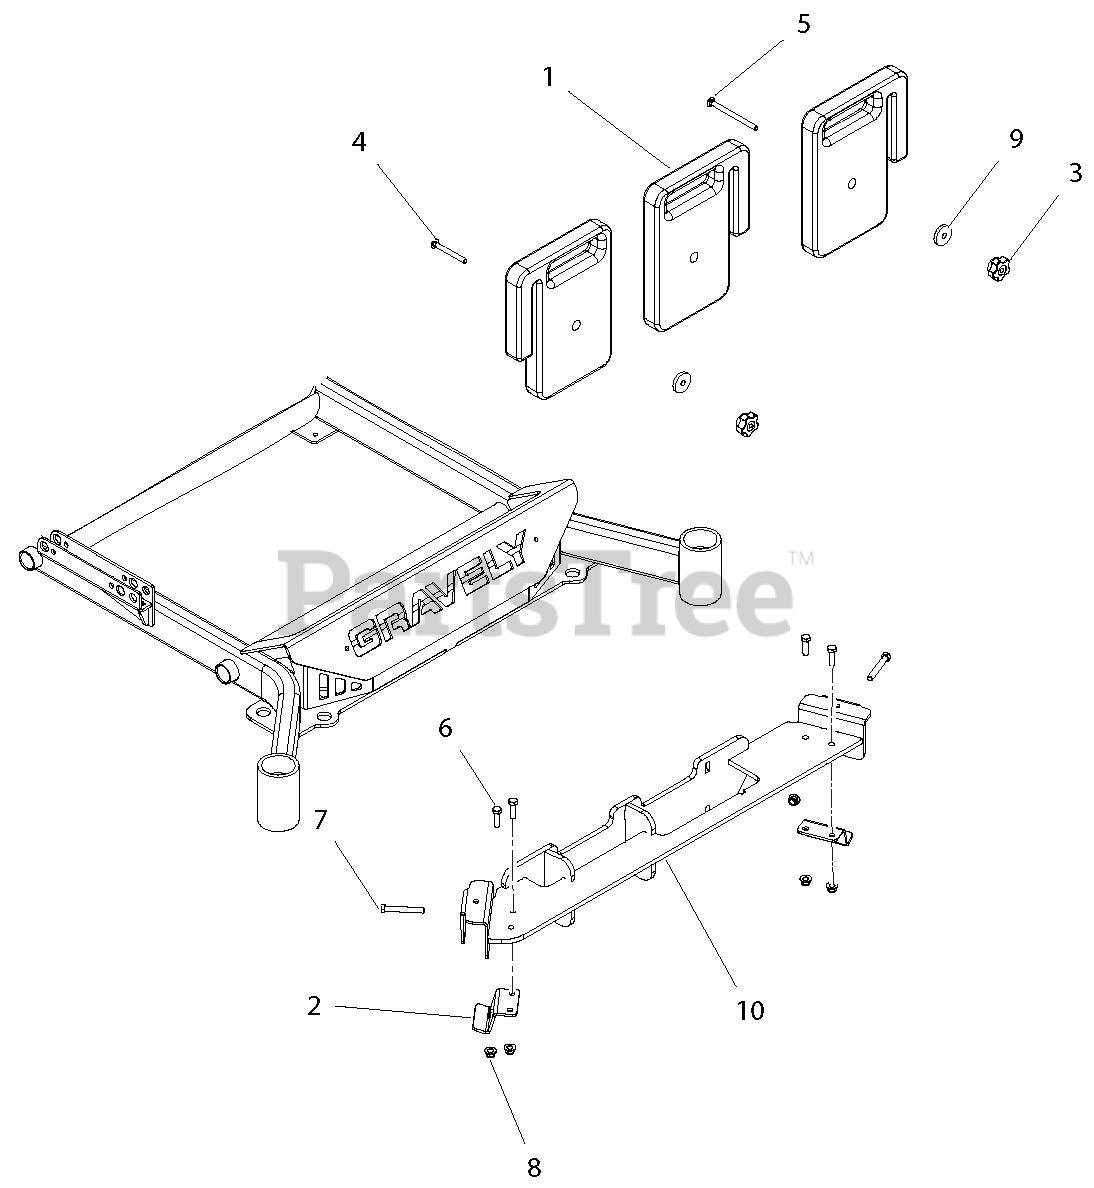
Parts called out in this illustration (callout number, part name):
1	WEIGHT, REAR
2	CLAMP, WEIGHT PLATE
3	KNOB, CLAMPING
4	@BLT-RDHDSQNK .31-18X3.00 G5YZ
5	BLT-RDHDSQNKFTH .31-18X4.50 G5
6	@BLT-HEX .38-16X1.25 GR5 YWZC
7	@BLT-HEX .38-16X2.75 GR5 YWZC
8	NUT-LK-NYL-FLG .38-16 YWZC
9	WSHR-FL-STL .406X1.50X.245 YWZC
10	WLDMT, PT200/400 BAGGER WEIGHT
